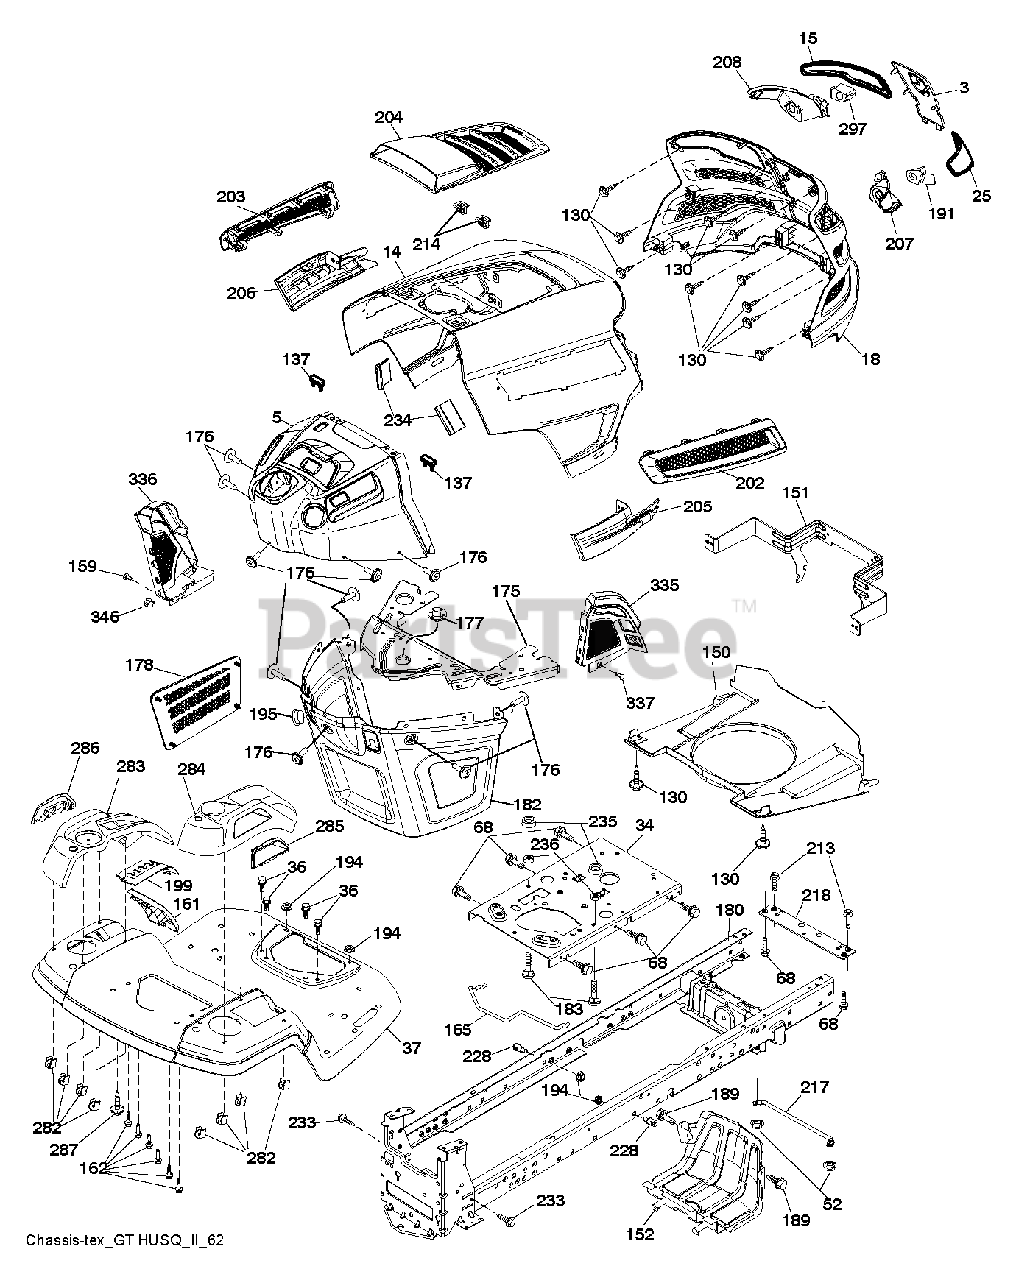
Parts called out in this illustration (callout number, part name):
3	APPLIQUE.SUBASM.GT.HUSQ.II
5	DASH.UPR.ASSY.GT2.SRVMNDER.PTO
14	HOOD.ASM.HUSQVARNA.GT.TEX.ORAN
15	LENS.HEADLIGHT.LH.GTII.2011
18	GRILLE.SUBASM.GT.HUSQ.II
25	LENS.HEADLIGHT.RH.GTII.2011
34	PLATE.ENGINE.WELDED.CHASSIS
36	SCREW 5/16"
37	FENDER.TLT.FS.W/CPH/FW/RSF.668
52	LOCKNUT
68	SCREW LT
130	SCREW.#10 X 0.750.BOS
137	BUMPER DASH
150	AIR.DUCT.GTV.BLACK
151	BRACKET.PIVOT.HOOD.GT.HUSQ.II
152	SHIELD.BROWNING.PNT.GT.V2
159	SCREW, 3/8-16X3/4
161	WINDOW.FUEL.LT.HUSQ.TEX.498
162	SCREW.HI-LO.CONSOLE
165	SUPPORT.TANK.REAR.W/TEX
175	PLATE.CROSSMEMBER.HUSQ
176	SCREW.#10-24X5/8.RN.QU
177	BUSHING, STEERING
178	CARGO.ASM.NET.TXGT.W/C
180	CHASSIS
182	DASH.LOWER.COMMON.12V.ADAPTOR
183	BOLT.5/16-18X1-1/4 FULL THD
189	SCREW
191	INSERT.REFLECTIVE.RH.HUSQ.GTII
194	NUT LOCK HEX FLANGE 5/16-18
195	PLUG.HOLE.DASH.LOWER.12V.BLK
199	PLATE.DECK.LIFT.HUSQ.LT
202	VENT.SIDE.RH.GT.HUSQ.II.
203	VENT.SIDE.LH.GT.HUSQ.II.498
204	VENT.TOP.HUSQ.GT2
205	SIDE.TRIM.RH.GT.HUSQ.II
206	SIDE.TRIM.LH.GT.HUSQ.II.GRAY
207	BEZEL LIGHT.RH.GT.II.MYLAR
208	BEZEL LIGHT.LH.GT.II.MYLAR
213	BOLT
214	CLIP.RETAINER.TINNER.
217	ROD.PIVOT.HOOD
218	X-PIECE.HOOD.STOP.NON/
228	STUD.FASTNER.W/ANTI-ROTATE
233	BOLT.SHOULDER
234	BUMPER.HOOD.TEX.HUSQVARNA
235	SPACER FENDER
236	NUT.CENTERLOCK.5/16-
282	CLIP.RETAINER.CONSOLE.LT.HUSQ
283	CONSOLE.DECK.LIFT.R.SDFL.HUSQ
284	CONCOLE.CNTRL.PDL.HUSQ.LT.498
285	CONSOLE INSERT RH
286	CONSOLE.INSRT.LH.HUSQ.LT.BLACK
287	SCREW 1/4X20
297	INSERT.REFLECTIVE.LH.HUSQ.GTII
335	COVER.RH.CLOSE.OUT.BLACK
336	COVER-LH.LOWER.DASH.GT2.BLACK
337	CLIP.XMAS.TREE.ITW.2622-00
346	CLIP,INSULATOR
